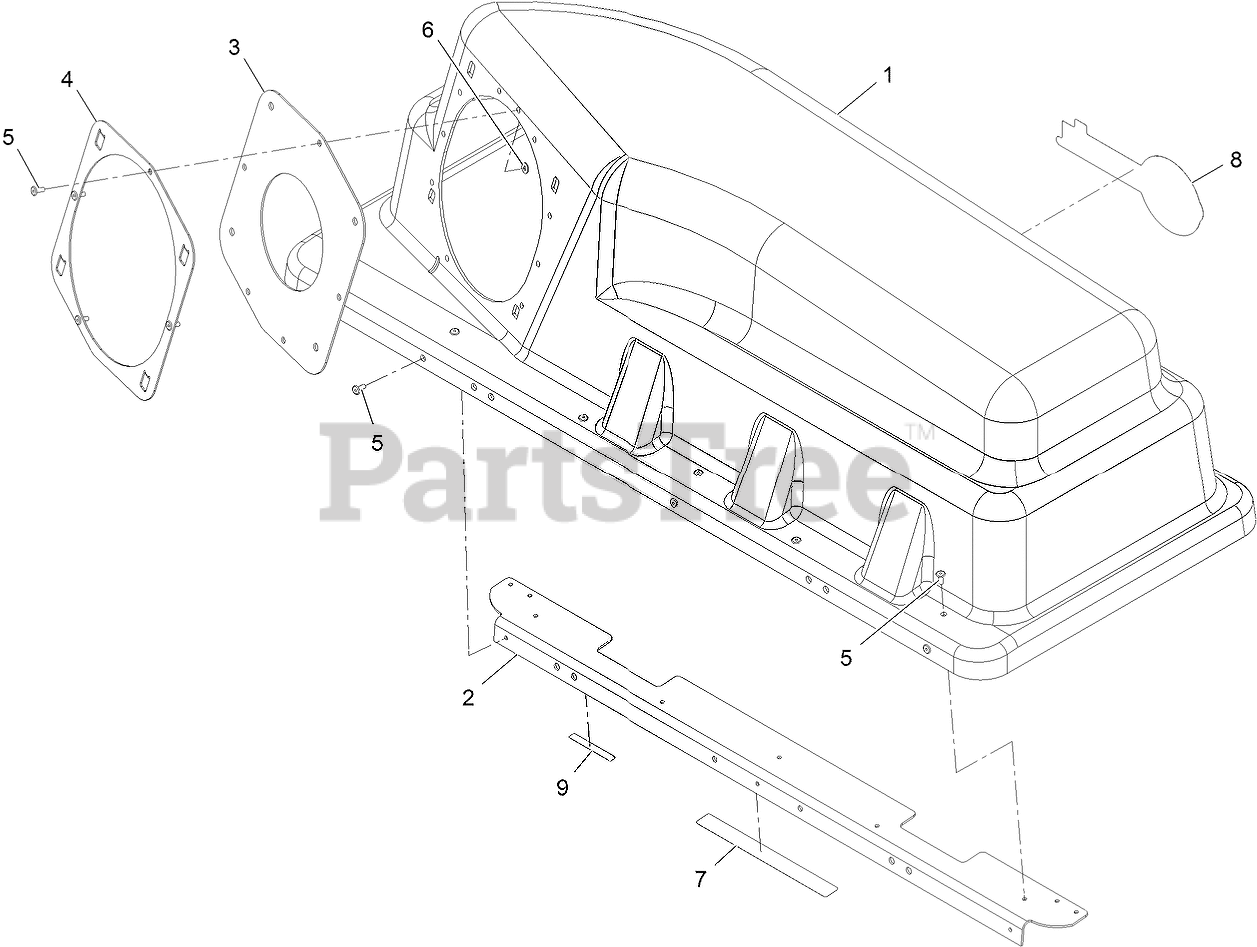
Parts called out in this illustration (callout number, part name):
1	TOP-BAGGER
2	STIFFENER-BAGGER, TOP
4	RING-RETAINER
5	RIVET-BLIND
6	WASHER-FLAT
7	DECAL-CRUSH HAZARD BAGGER
8	DECAL-EXMARK LOGO
9	DECAL-WARNING
